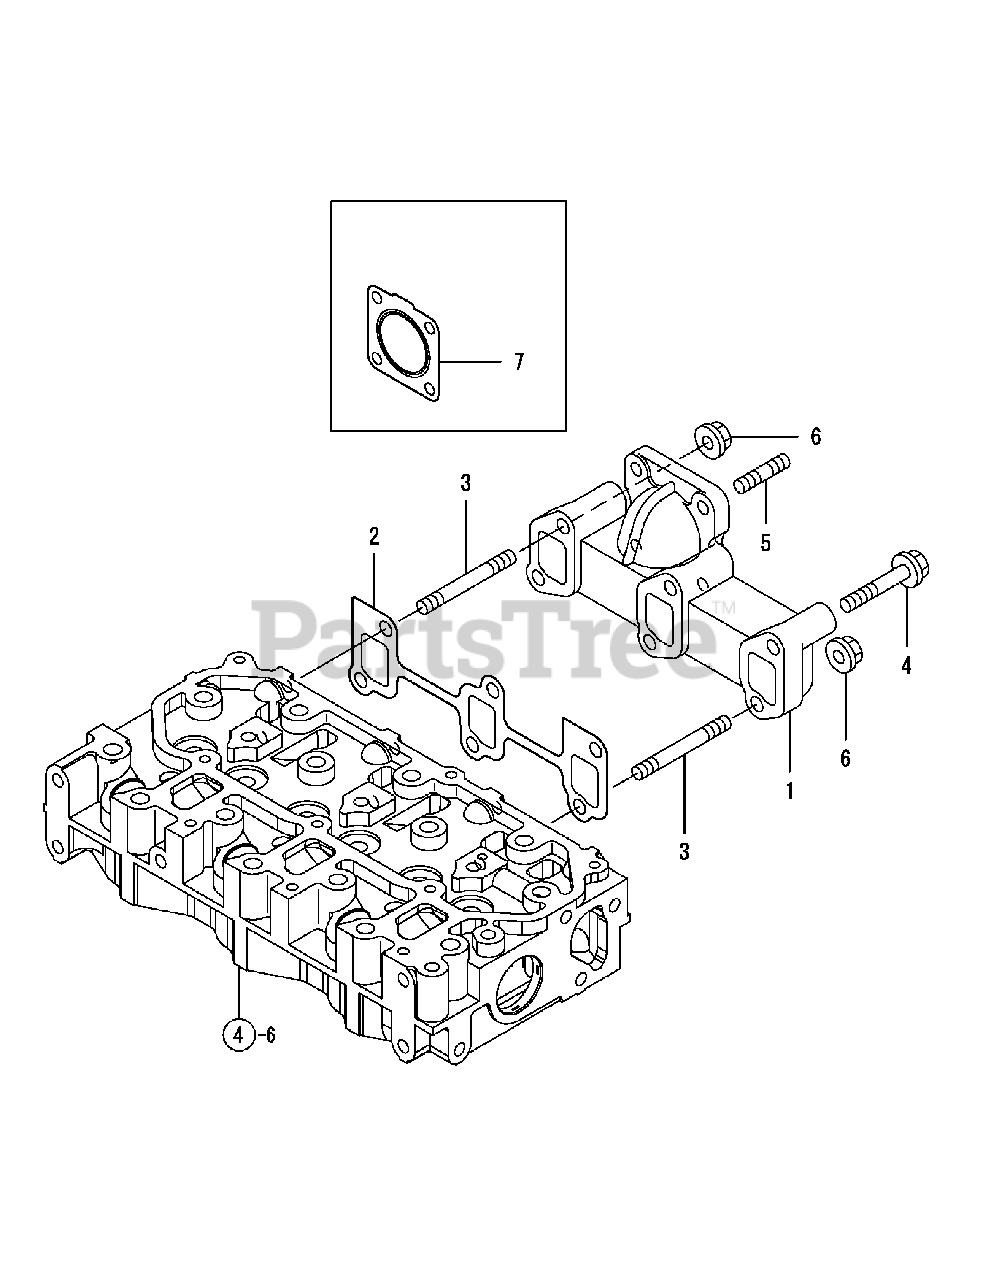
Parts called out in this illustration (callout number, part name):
1	Manifold, Exhaust
2	Gasket, Manifold
4	Bolt, M 8 x 50 Plated
5	Bolt, M 8 x 22
7	Gasket, Silencer
